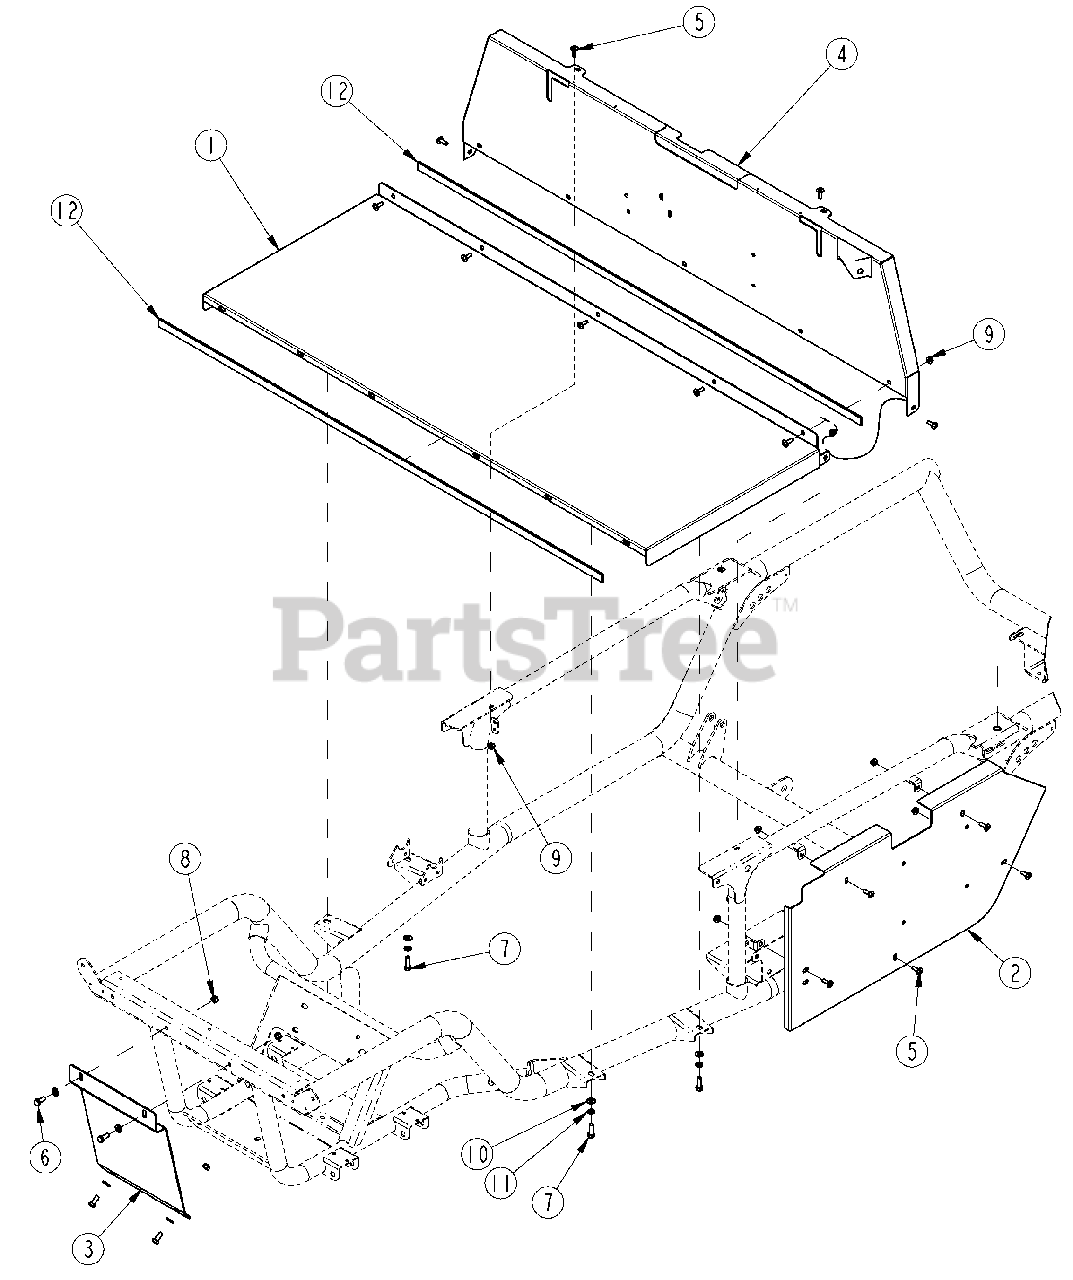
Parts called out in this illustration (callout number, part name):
1	FLOOR WIDE WELDMENT
2	SIDE PANEL, WIDE
3	FRONT FRAME GUARD ST
4	KICK PANEL WLDMNT (ST)
5	TPHMS Y 1/4-20 X 3/4 YELLOW DIE
6	BOLT, HEX 5/16-18 X 3/4 GR5 YELLOW DI
7	BOLT, HEX 5/16-18 X 1 GR5
8	NUT, NYLON LOCK 5/16-18
9	NUT HEX FLNG T-LOCK 1/4-20 PLT
10	WASHER, FLAT 5/16 HARDENED ASTMF436
11	WASHER, LOCK SPRING 5/16 YELLOW
12	FOAM RUBBER 3/16 X 3/4 THK W/PSA 52.5" Lg.
